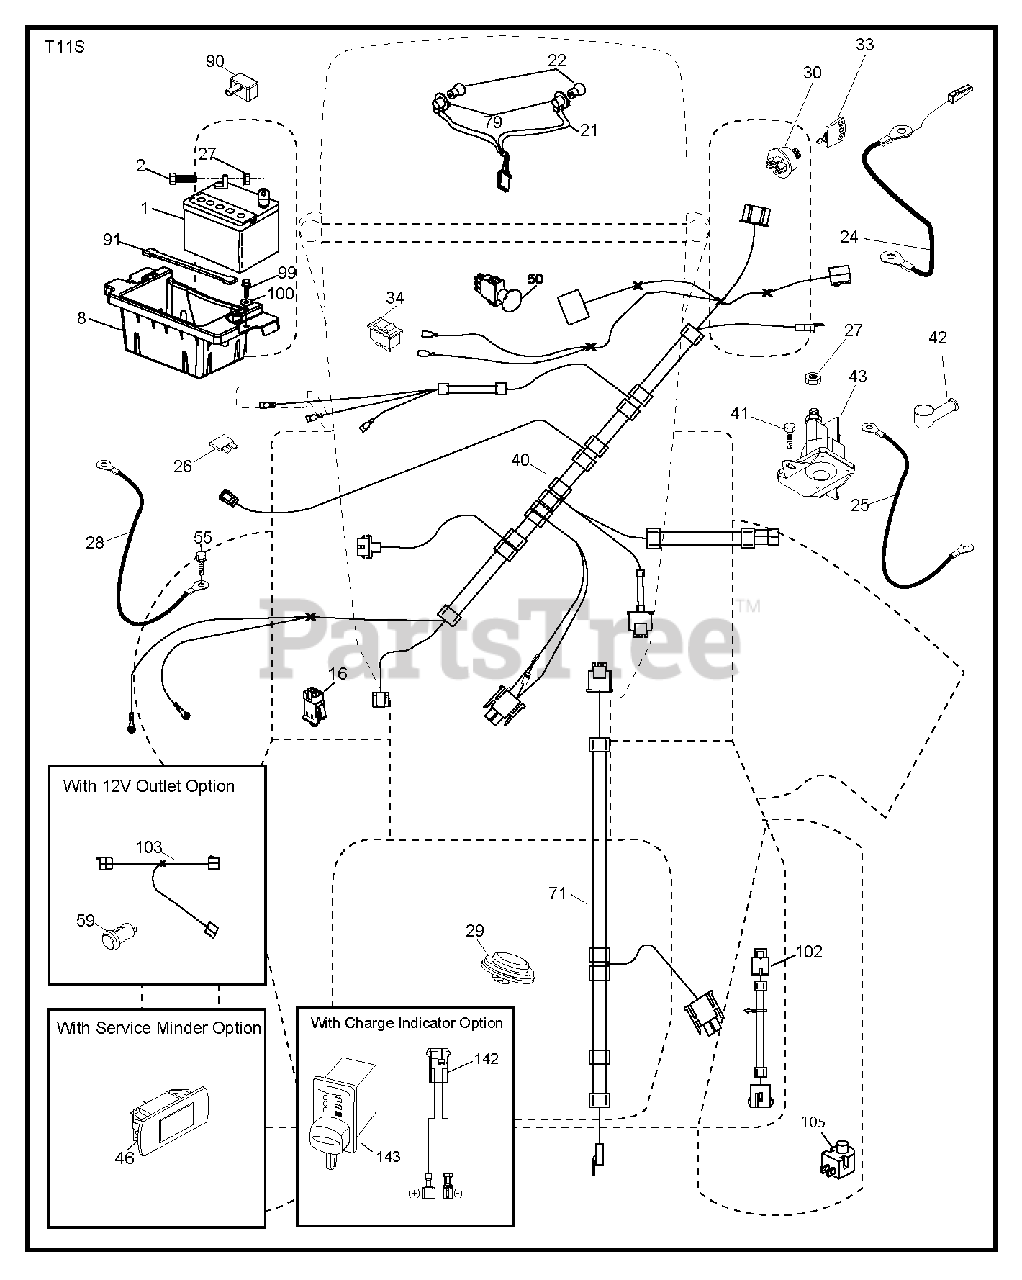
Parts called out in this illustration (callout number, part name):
1	REPL BY 532 12 38-99
8	BOX.BATTERY.MOUNT.FRONT.LT
16	SWITCH INTERLOOK PUSH-IN
21	HARNESS.LIGHT W/4152J BULBS
22	LIGHTBULB
24	Battery Cable with Wire, Front 8 Ga 8
25	Starter Cable, 8 Ga 17.5"
26	FUSE 20AMP
27	NUT
28	Ground Cable, 21" Black 8 Ga 90T
29	SWITCH.SEAT.DELTA.OPC.
30	SWITCH.IGN.DELTA.W.LGH.ROS
33	KEY.CHAIN.BLISTER.PACK.GEN.USA
34	SWITCH LT
40	HARNESS.IGN.DASH.HUQ/P
41	SCREW
42	TERMINAL COVER
43	SOLENOID.W/BRASS.PLUNG
46	Hour Meter Gauge
50	PTO SWITCH
55	SCREW 5/16"
71	HARNESS-CHASSIS SUB
79	BULB HOLDER ASM.
90	COVER.TERMINAL.BATTERY
91	STRAP, BATTERY MOUNT
99	SCREW HEXWSHR 1/4-20X3/4
102	HARNESS PIGTAIL PCH TEX ROS
105	REVERSE SWITCH
